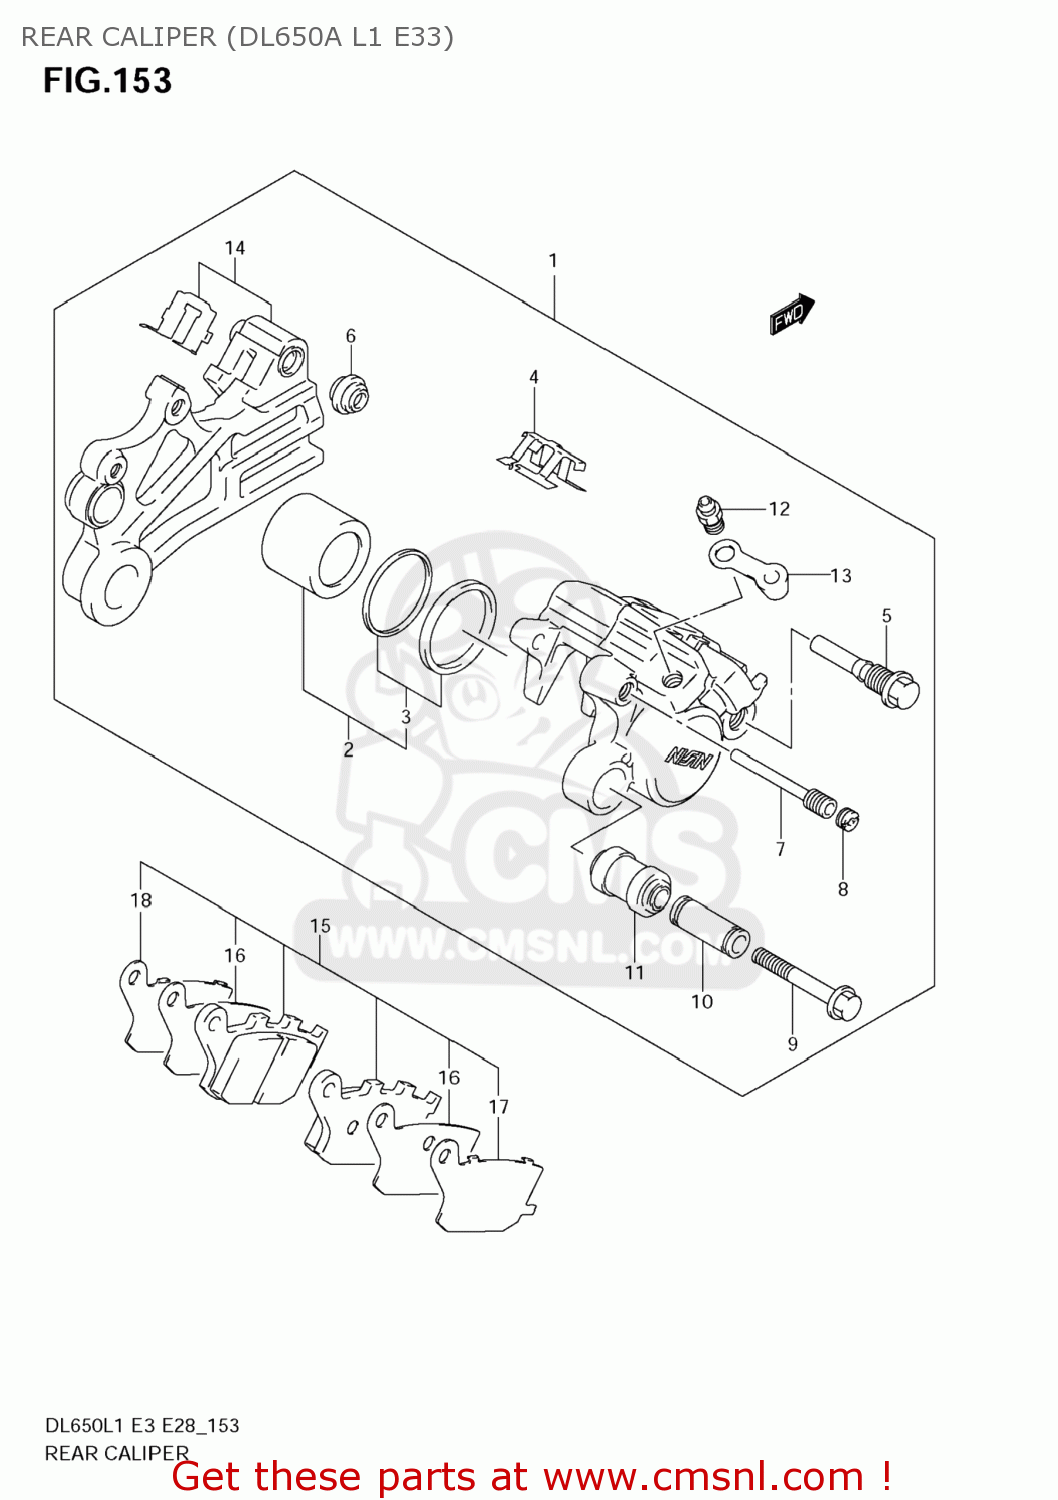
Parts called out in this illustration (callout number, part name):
1	CALIPER ASSY,RR
2	PISTON SET
3	SEAL SET,PISTON
4	SPRING,PAD
5	BOLT
6	BOOT
7	PIN,PAD
8	PLUG,PIN
9	BOLT
10	SLEEVE
11	BOOT,SLEEVE
12	BLEEDER
13	CAP,BLEEDER
14	BRACKET
15	PAD & RETAINER SET
16	INSULATOR
17	RETAINER
18	RETAINER
